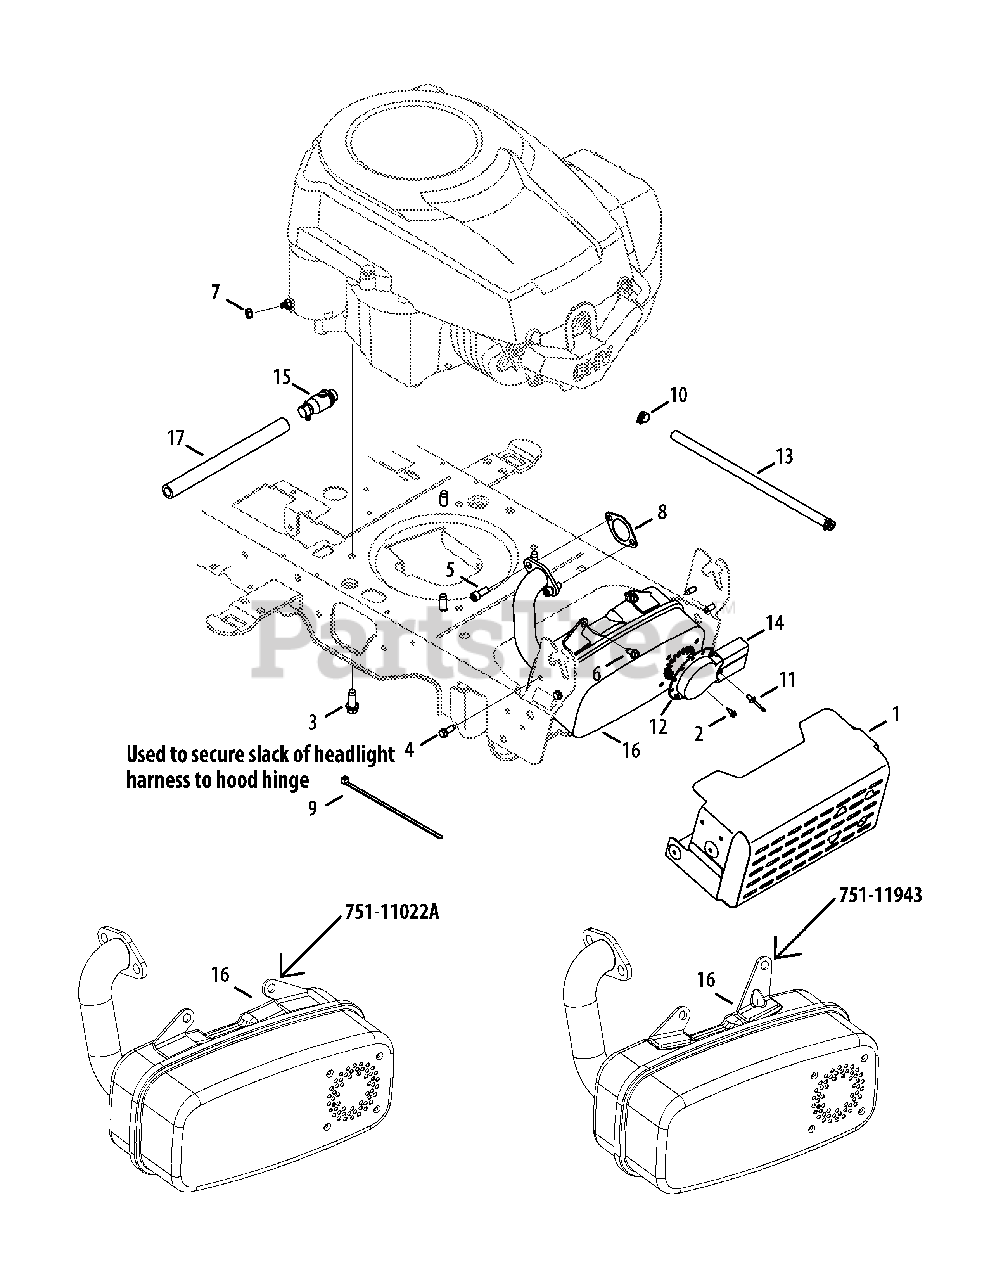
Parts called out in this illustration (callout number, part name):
1	Shield Ass’y, Muffler
2	Screw, Ab, #8-18, 0.500,
3	Screw, Self-tapping, 3/8-16, 1.000,
4	Screw, Self-tapping, 1/4-20, 0.500,
5	Screw, Socket Head, 5/16-18, .750
6	Screw, Self-tapping, 1/4-20x.625,
7	Nut, Sems, 1/4-20
8	Gasket, Exhaust
9	Cable, Tie, 3/16 x .05 x 7.4
10	Clamp, Hose, .490 Dia.
11	Rivet, Pop, .188 Dia x .300
12	Deflector, Muffler
13	Hose, Fuel, Low Permeation, 1/4
14	Deflector, Muffler, Long
16	Muffler, Single, Kohler
17	Hose, Extension, Oil Drain
